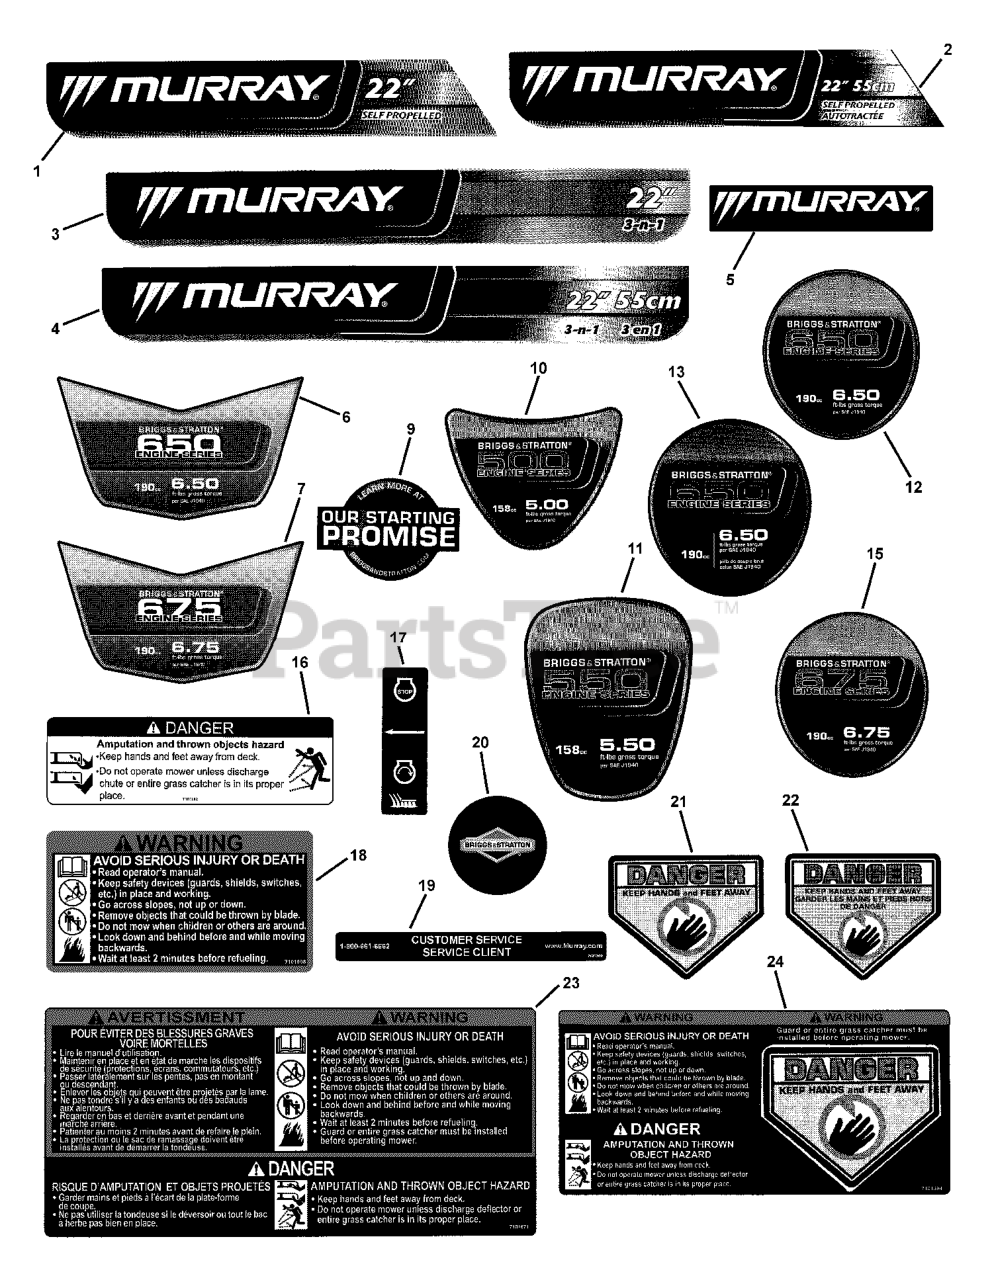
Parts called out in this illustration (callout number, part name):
1	DECAL, Murray Logo, Deck
2	DECAL, Murray Logo, Deck, SS, FC
3	DECAL, Murray Logo, Deck
4	DECAL, Murray Logo, Deck, Push, FC
5	DECAL, Murray Logo, Deck
6	DECAL, Engine, Murray, TP, 650, Cailf.
7	DECAL, Engine, Murray, TP, 675, Cailf.
9	DECAL, Starting Promise
10	DECAL, Engine, Murray, TP, 500
11	DECAL, Engine, Murray, TP, 550
12	DECAL, Engine, Murray, TP, 650
13	DECAL, Engine, TP, 650, Murray, FC
15	DECAL, Engine, Murray, TP, 675
16	DECAL, Danger, Deck, MY 07.5
17	DECAL, OPC Bail International Symbol
18	DECAL, Warning, Walk-Behind Mower
19	DECAL, Customer Service, Murray
21	DECAL, Danger, Cut Finger
22	DECAL, CPSC, French/English
23	DECAL, WB Safety, French/English
24	DECAL, Warning, Rear Discharge Door
